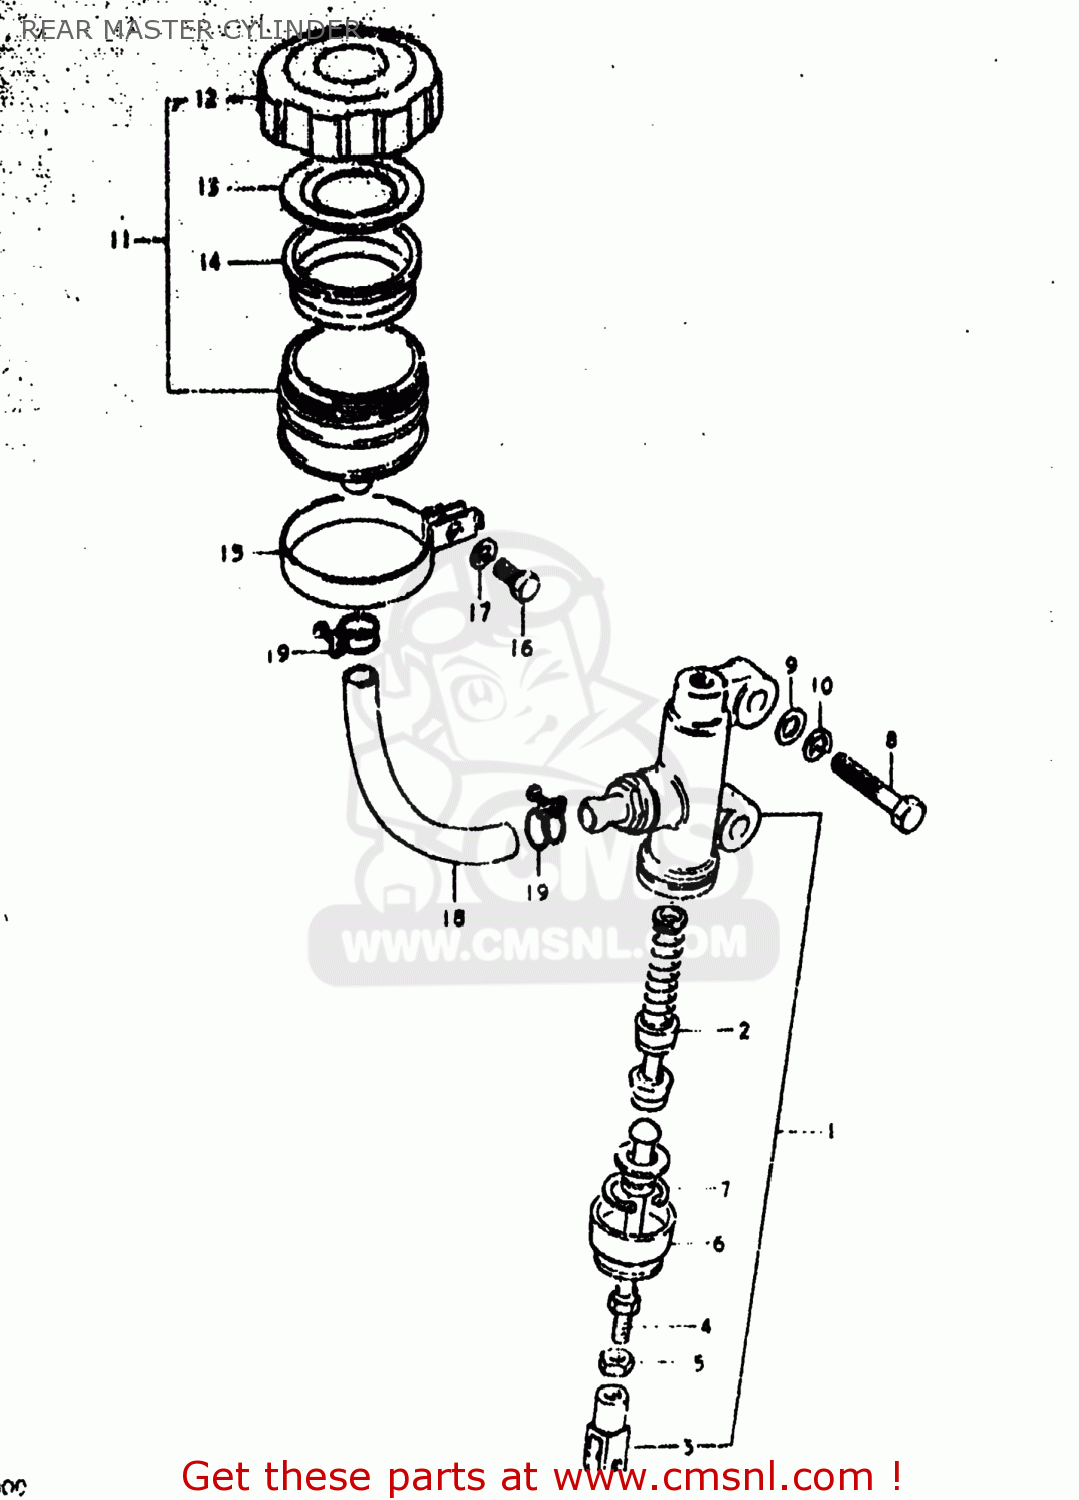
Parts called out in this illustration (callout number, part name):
1	CYLINDER ASSEMBLY,REAR MASTER
2	PISTON/CUP SET
3	YOKE
4	ROD,PUSH
5	NUT
6	BOOT
7	CIRCLIP
8	BOLT (8X30)
9	WASHER
10	LOCK WASHER
11	TANK ASSEMBLY,RESERVOIR
12	CAP
13	PLATE,DIAPHRAGM
14	DIAPHRAGM
15	CLAMP
16	BOLT, UPPER
17	LOCK WASHER
18	HOSE,RESERVOIR TANK
19	CLAMP
